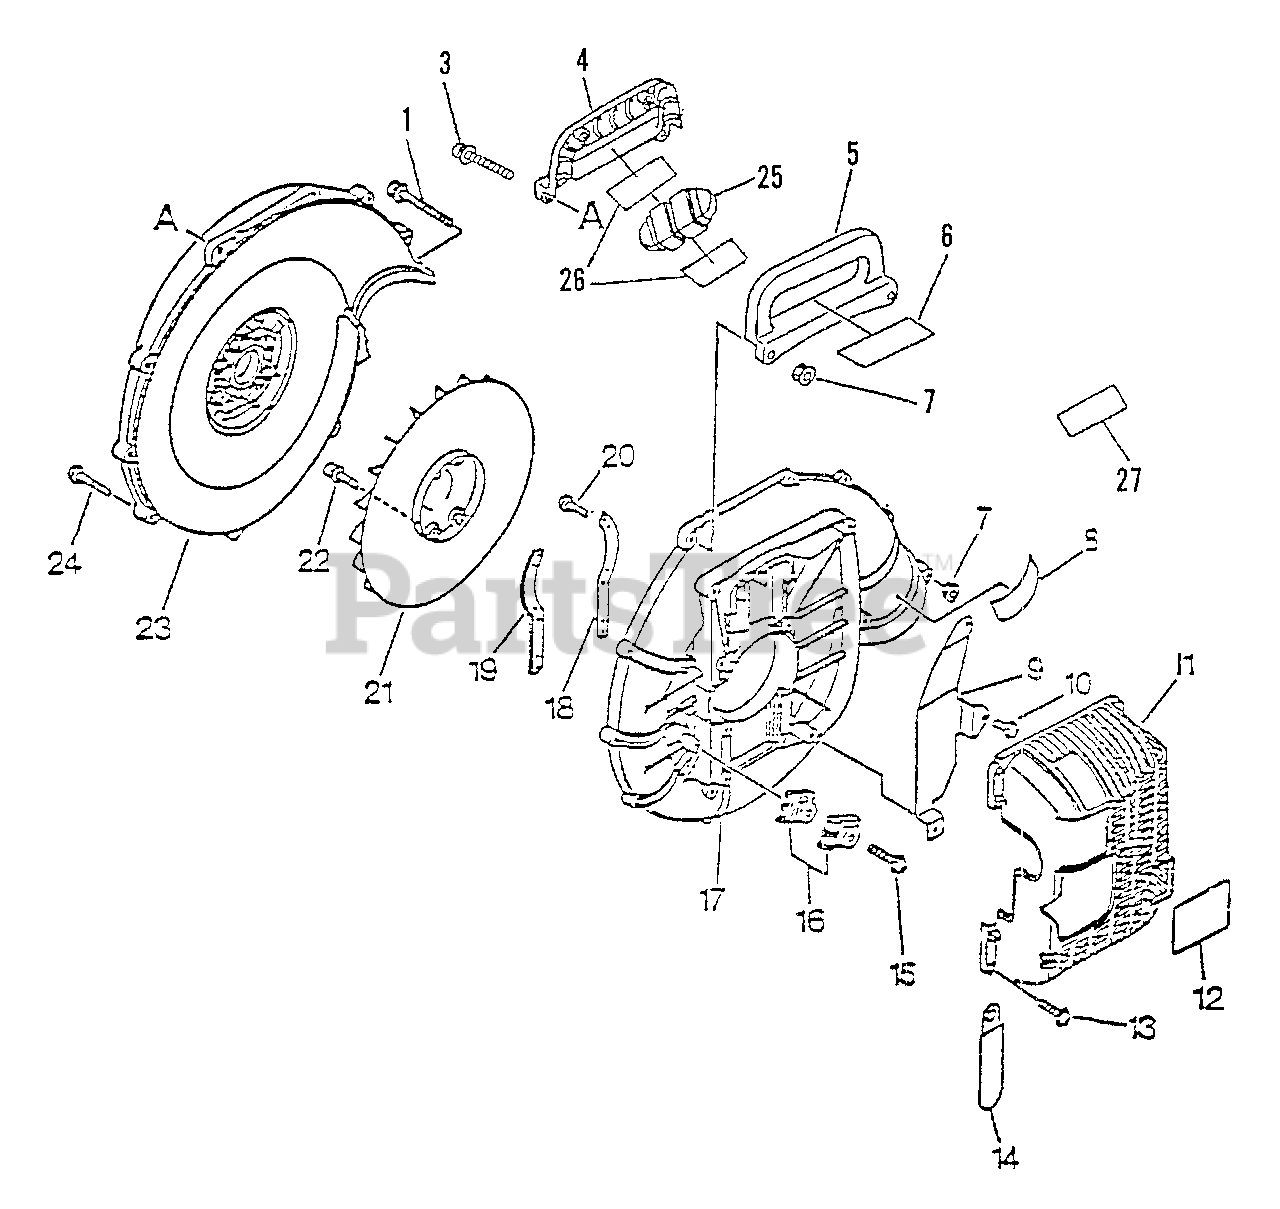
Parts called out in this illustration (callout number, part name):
1	BOLT 5×60
3	SCREW 5×45
4	HANDLE, REAR
5	HANDLE, REAR
6	LABEL, CAUTION
7	NUT, FLANGE M5
8	LABEL - MODEL
9	INSULATOR
10	BOLT 5×20
11	COVER, ENGINE
12	LABEL, LBB-4200
13	BOLT 5×20
15	SCREW 5×25
16	CABLE HOLDER KIT
17	COVER, FAN - OUTER
18	BRACKET, ENGINE
19	BRACKET, ENGINE
20	SCREW, TAPPING 3×8
22	BOLT 5×20
23	COVER, FAN - INNER
24	SCREW 5×30
27	LABEL - NOISE
